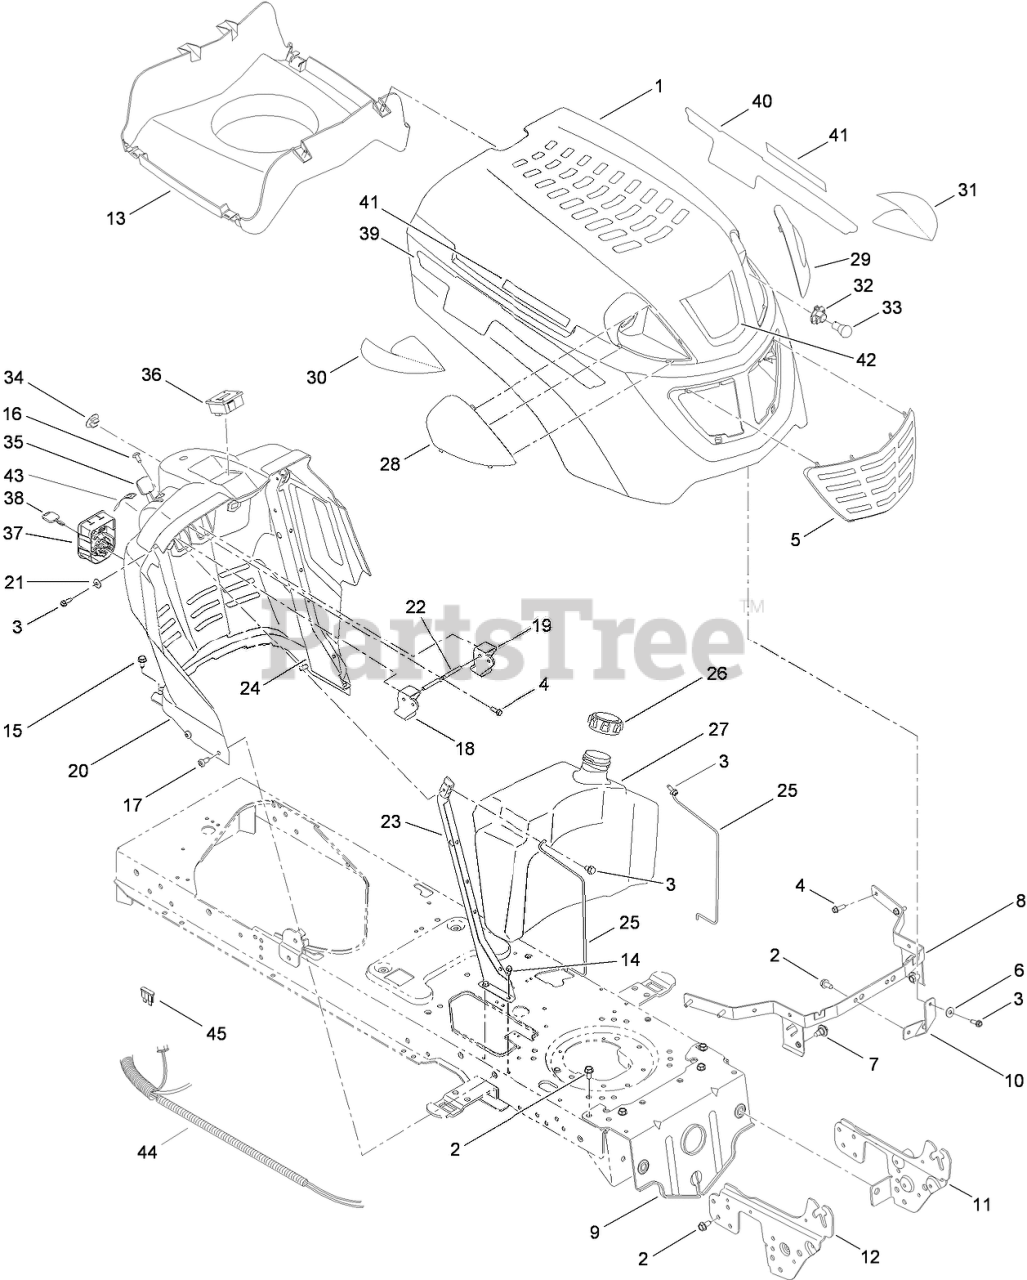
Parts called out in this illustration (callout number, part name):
2	SCREW-TAP
3	SCREW-TAP
4	SCREW-TAP
6	WASHER-FLAT
7	BOLT-SHOULDER, TAP
8	BRACKET-PIVOT
9	BRACKET-PIVOT
10	BRACKET-SUPPORT, HOOD
11	BRACKET-SUPPORT, PIVOT (LH)
12	BRACKET-SUPPORT, PIVOT (RH)
13	PLENIUM-HOOD
14	SCREW-HWHTF
15	SCREW-TAP
16	SCREW-TAP
17	SCREW-TAP
18	LEVER-CRUISE
19	LEVER-BRAKE
20	DASH-MANUAL, PTO
21	WASHER-SPRING
22	ROD-LEVER, BENT
23	SUPPORT-DASH, PLATE (RH)
24	SUPPORT-DASH, PLATE (LH)
25	ROD-SUPPORT
26	CAP-FUEL
27	TANK-FUEL, 3 GAL
28	LENS-RH
29	LENS-LH
30	REFLECTOR-RH
31	REFLECTOR-LH
32	SOCKET-HEADLIGHT
33	LAMP-12V, MINIATURE
34	PLUG-CHOKE
35	CABLE-THROTTLE/CHOKE
36	METER-HOUR
37	MODULE-SWITCH, IGNITION
38	KEY-IGNITION
39	DECAL-HOOD, RIGHT SIDE
40	DECAL-HOOD, LEFT SIDE
42	DECAL-HOOD
43	DECAL-THROTTLE
44	HARNESS-WIRING
45	FUSE-20 AMP
